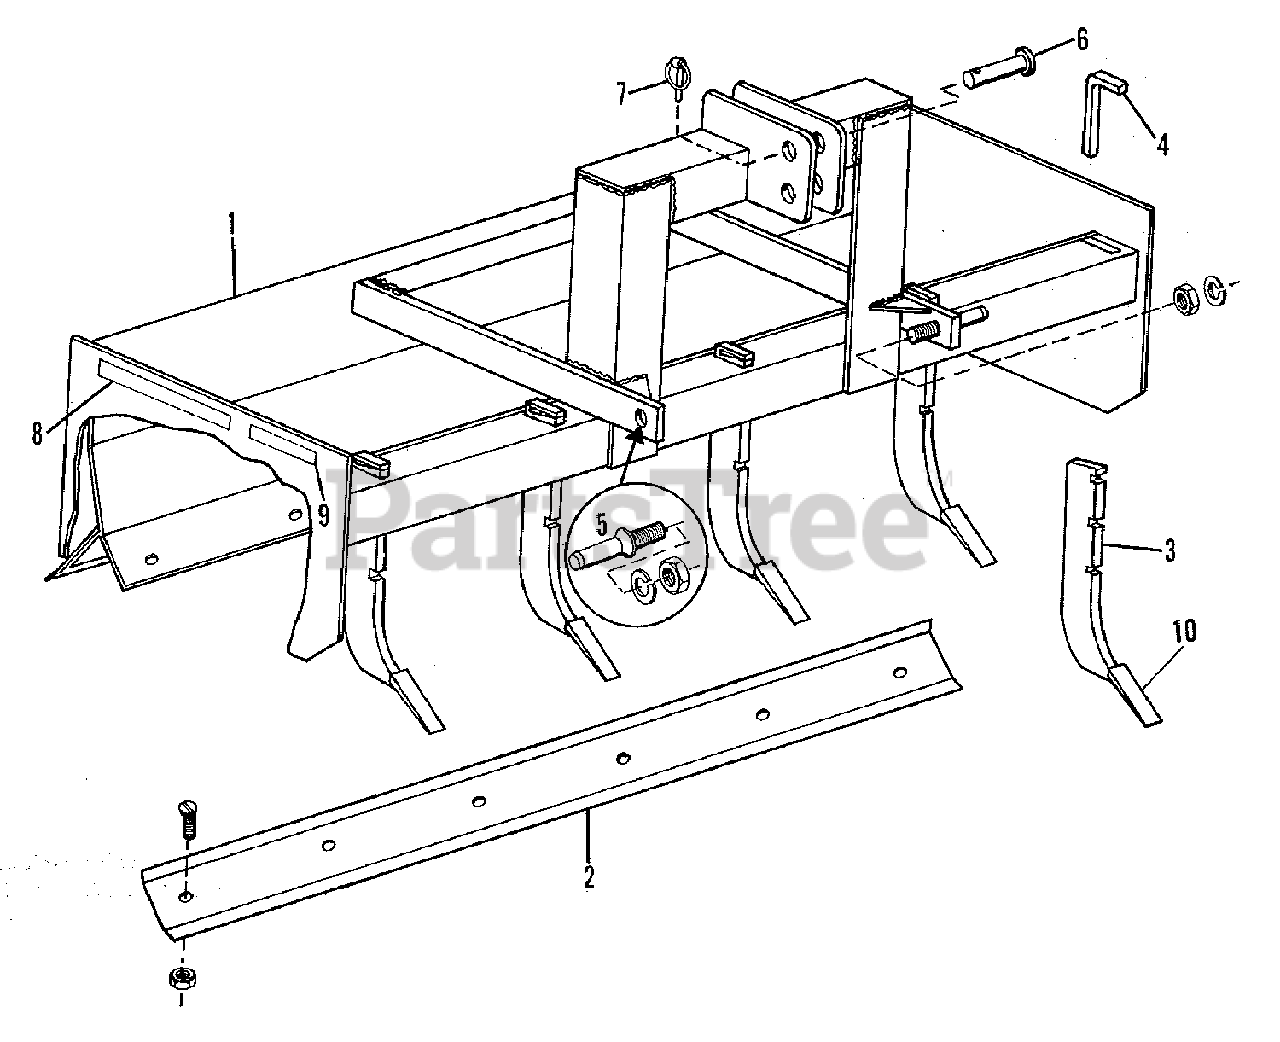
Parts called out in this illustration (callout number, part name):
1	FRAME ASSEMBLY
2	BLADE, Cutting
2	BOLT, Plow, No. 3 Head, 5/8NC x 2-1/2
2	LOCKWASHER, 5/8
3	SHANK ASSEMBLY
4	PIN, Locking
5	PIN, Link (Cat. l)
5	LOCKWASHER, 7/8
6	PIN, Hitch, Upper
8	DECAL (Allis-Chalmers)
9	DECAL (48 Model Identification)
10	POINT, Scarifier
